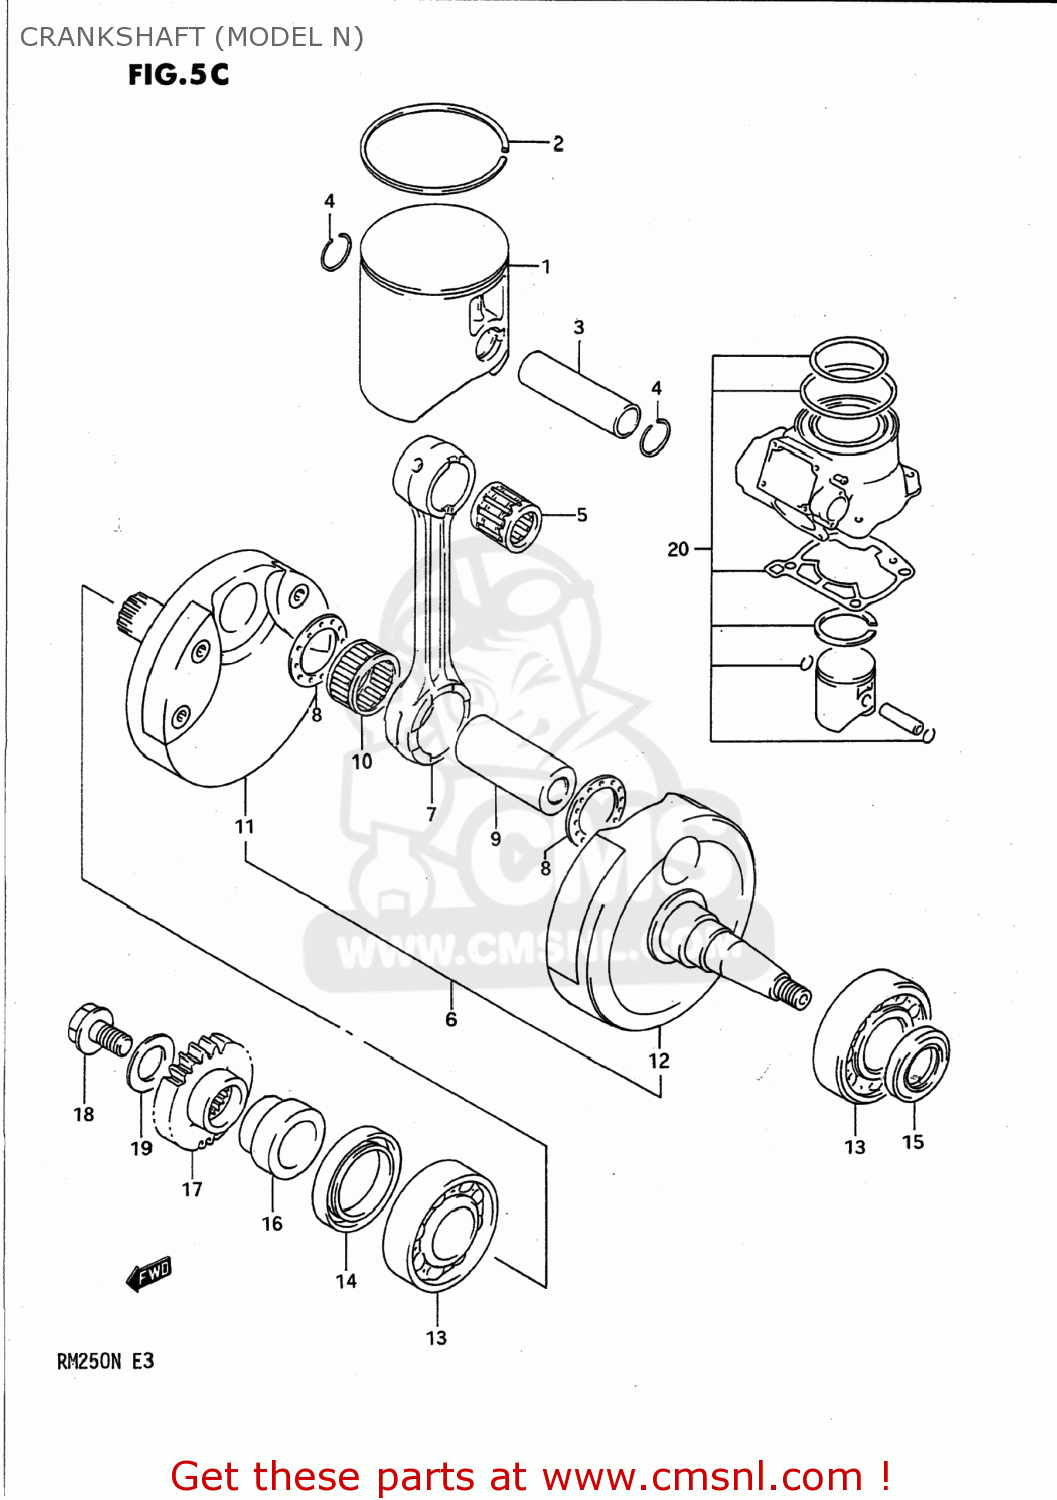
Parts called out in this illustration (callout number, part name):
1	PISTON
2	RING,PISTON
3	PIN,PISTON
4	CIRCLIP
5	BEARING(18X23X22)
6	CRANKSHAFT ASSEMBLY
7	ROD,CONNECTING
8	WASHER(24X38.5X1.5)
9	PIN,CRANK
10	BEARING(24X30X20)
11	CRANKSHAFT
12	CRANKSHAFT,LEFT
13	BEARING(25X62X17)
14	SEAL,OIL(36X52X7)
15	SEAL,OIL(20X37X6)
16	SPACER,PRIMARY DRIVE GEAR
17	GEAR,PRIMARY DRIVE
18	BOLT,PRIMARY DRIVE GEAR
19	WASHER
20	TOP END KIT,ENGINE
